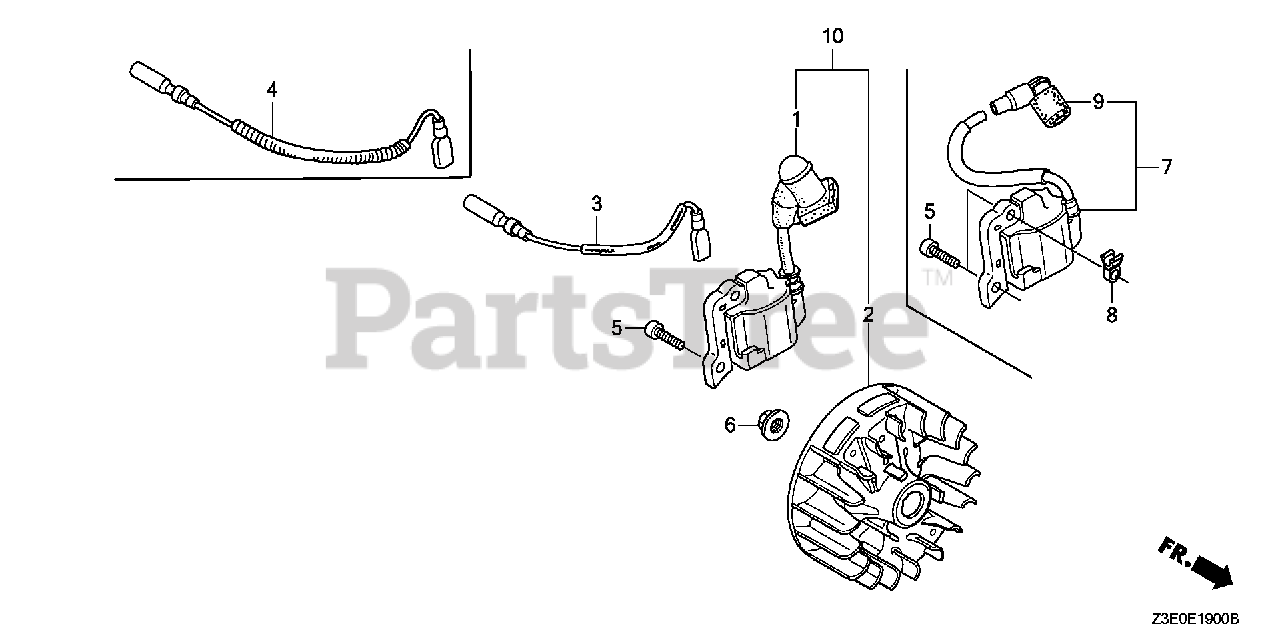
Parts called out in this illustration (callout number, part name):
1	COIL ASSY., IGNITION
3	WIRE, STOP SWITCH
5	BOLT, SOCKET (4X14)
6	NUT, FLANGE (7MM)
